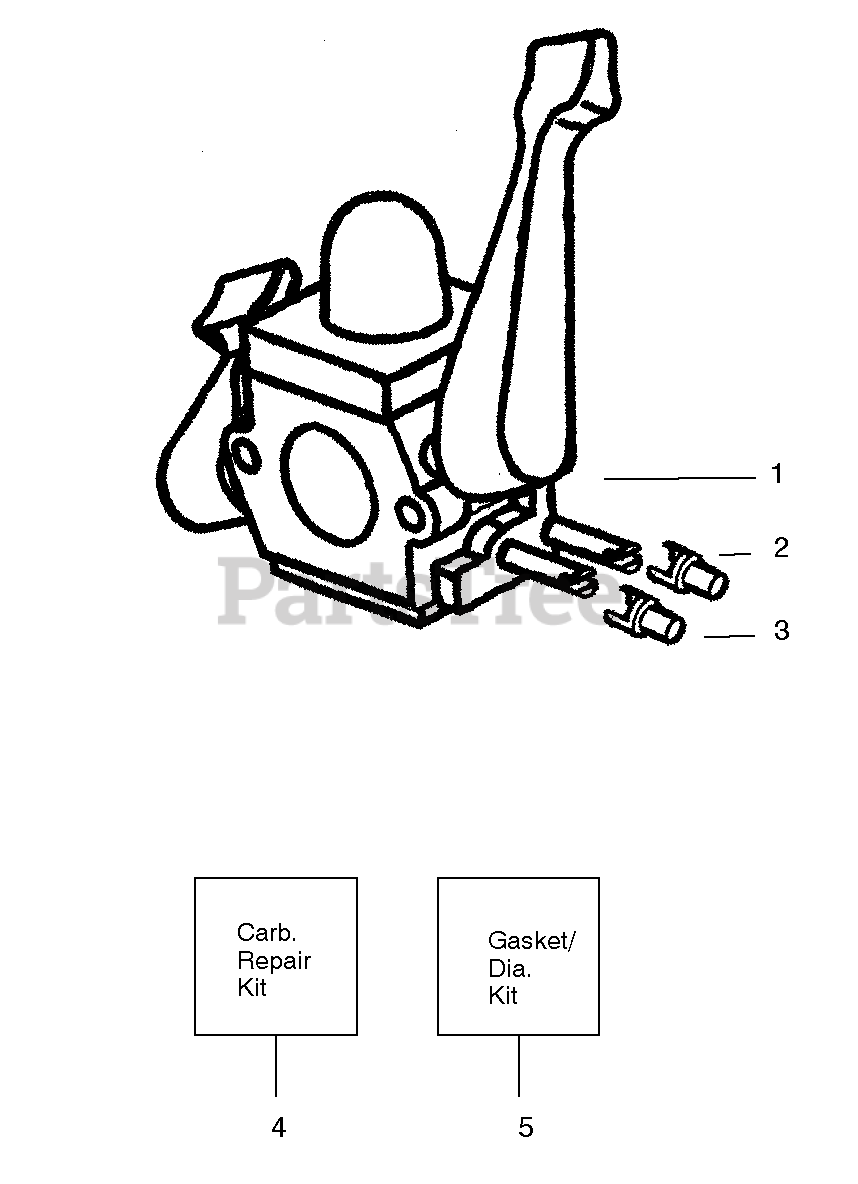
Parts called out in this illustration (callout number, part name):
1	Assy-Carb. Zama, (C1Q-W11)
2	Cap-Limiter (high) brown
3	Cap-Limiter (low) tan
4	Kit-Carb. Repair
5	Kit-Dia. (GND-34)
